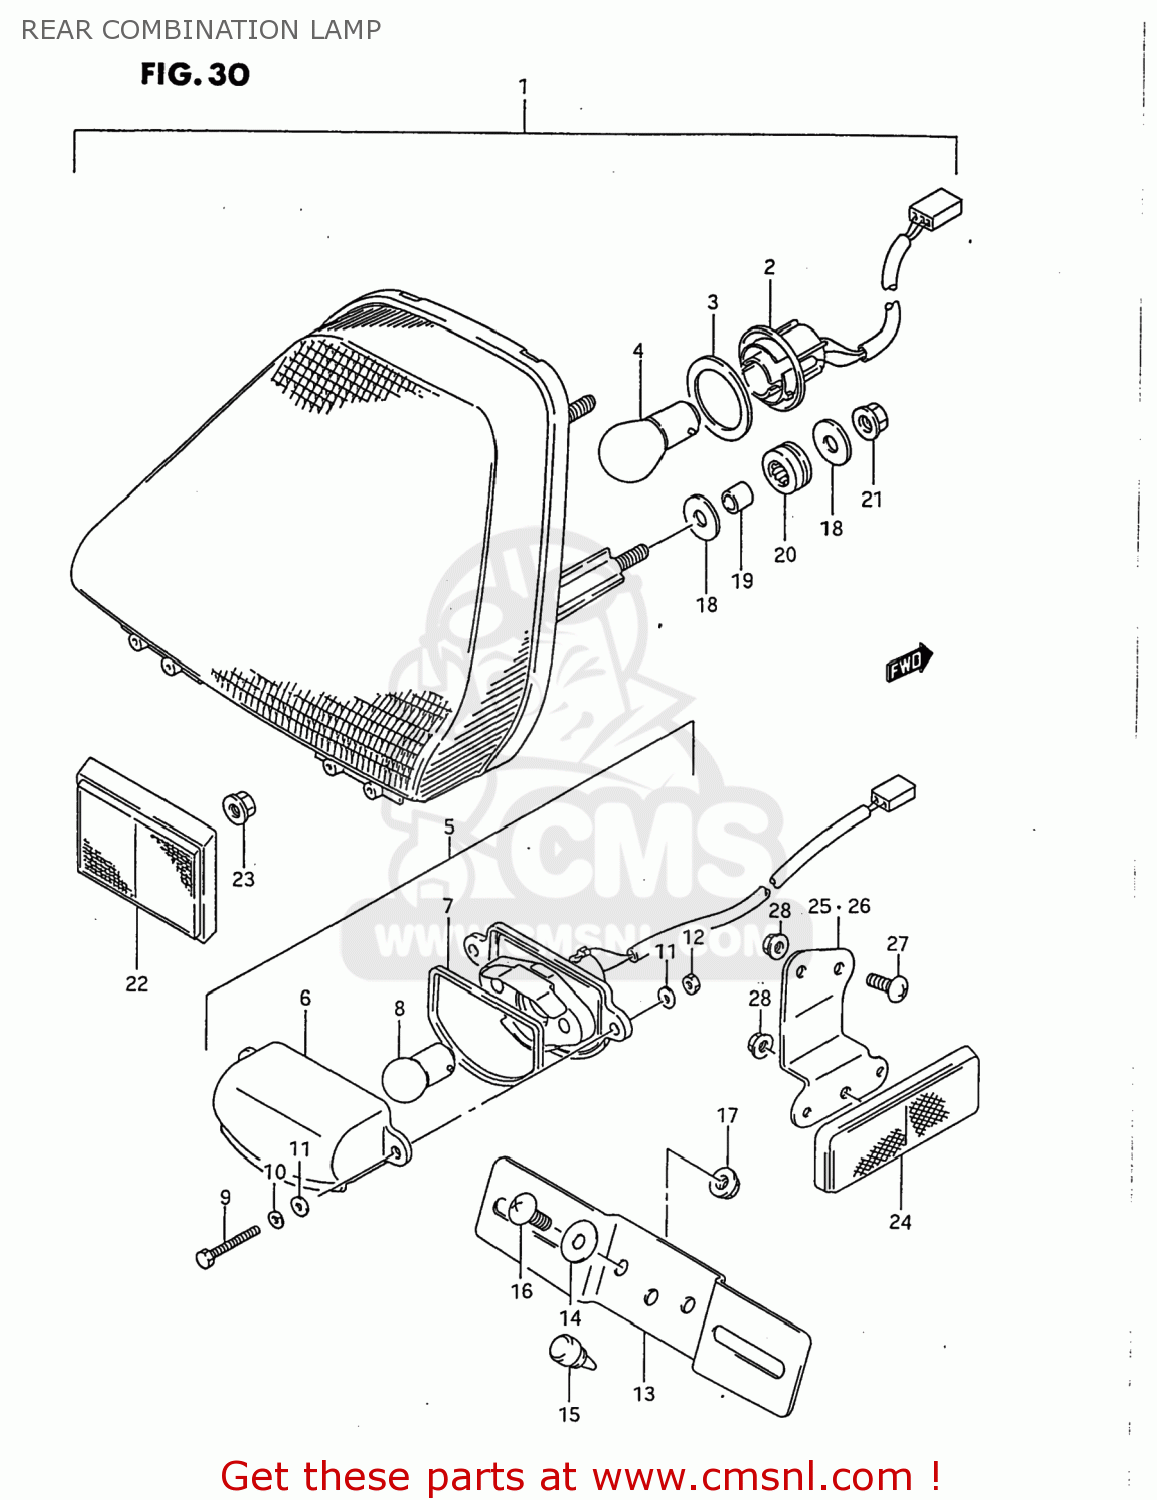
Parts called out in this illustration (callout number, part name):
1	LAMP ASSY,RR COMBINATION
2	SOCKET
3	CUSHION,RUBBER
4	BULB(12V21/5W,BF141-49642A)
5	LAMP ASSEMBLY,LICENSE
6	LENS,LICENSE LAMP
7	GASKET,LICESE LAMP (NAS)
8	BULB(12V8W)
9	BOLT
10	WASHER,LOCK
11	WASHER
12	NUT
13	BRACKET,LICENSE PLATE
14	WASHER
15	CUSHION
16	SCREW 6X16
17	NUT
18	WASHER(6.5X20X1.2)
19	SPACER(6.1X8X9.5)
20	CUSHION
21	NUT
22	REAR ASSEMBLY,REAR
23	NUT
24	REFLECTOR ASSEMBLY,REAR
25	BRACKET,RR SIDE RR,R
26	BRACKET,RR SIDE RR,L
27	SCREW 5X12
28	NUT
